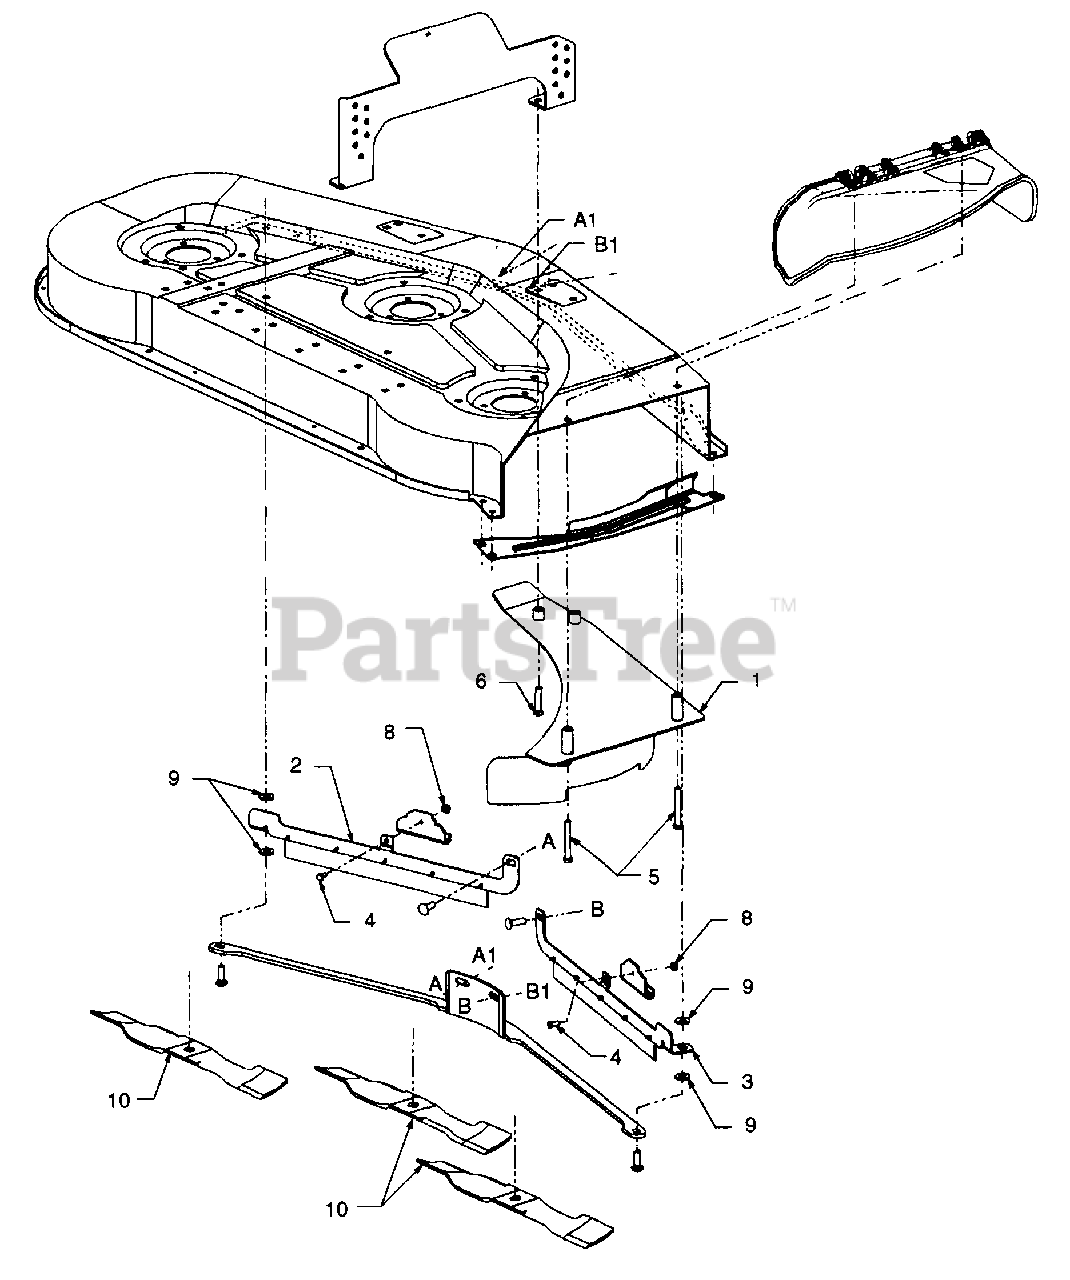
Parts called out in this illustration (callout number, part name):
1	Baffle Ass'y, 54" Mulching
5	Screw, Hex Cap, 3/8-16 X 2-3/4 GR5
6	Screw, Hex Cap, 3/8-16 X 1-3/4 GR5
8	Nut, Hex Flange Lock, 1/4-20
9	Washer, Flat, .406 X 1.0 X .105
10	Blade, Mulching, 18.5 Lg
